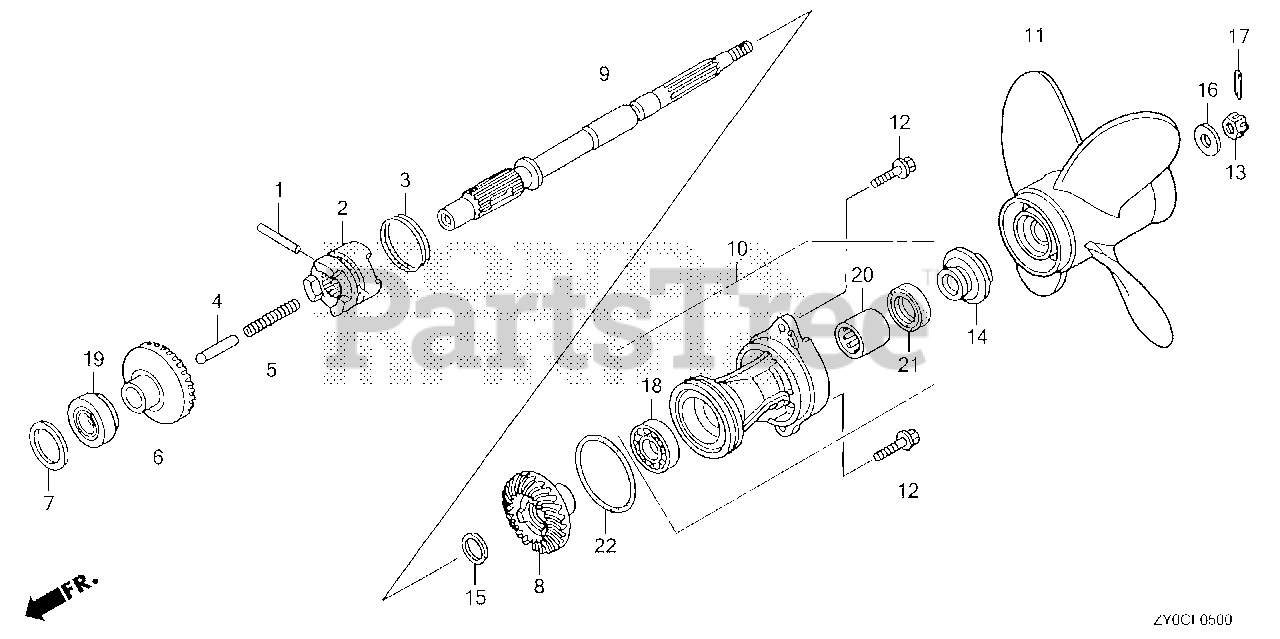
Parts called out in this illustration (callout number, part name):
1	ROLLER (4X29.8)
2	SHIFTER, CLUTCH
3	RING, CROSS PIN
4	SLIDER, SHIFT
5	SPRING, SHIFT
6	GEAR, FR. BEVEL
7	SHIM A (40MM)
7	SHIM B (40MM)
7	SHIM C (40MM)
7	SHIM D (40MM)
8	GEAR, RR. BEVEL
9	SHAFT, PROPELLER
10	HOLDER ASSY., PROPELLER SHAFT *NHB14M* (AQUA MARINE SILVER METALLIC)
11	PROPELLER, FOUR BLADES (9-1/4X7) *NH283*
11	PROPELLER, FOUR BLADES (9-1/4X8) *NH283* (STIN GRAY)
11	PROPELLER, FOUR BLADES (9-1/4X9) *NH283* (STIN GRAY)
11	PROPELLER, FOUR BLADES (9-1/4X10) *NH283*
11	PROPELLER, FOUR BLADES (10X7-5/8) *NH283* (STIN GRAY)
12	BOLT, FLANGE (6X20) (ENGINE NO.)
13	NUT, CASTLE (10MM)
14	WASHER, PROPELLER THRUST
15	WASHER (18MM)
16	WASHER (10MM)
17	PIN, COTTER (3MM)
18	BEARING, RADIAL BALL (25X47X12)
19	BEARING (25X47X15)
20	BEARING, NEEDLE (17X24X20) (NTN)
21	SEAL, WATER (17MM)
22	O-RING (59.4X3.1)
